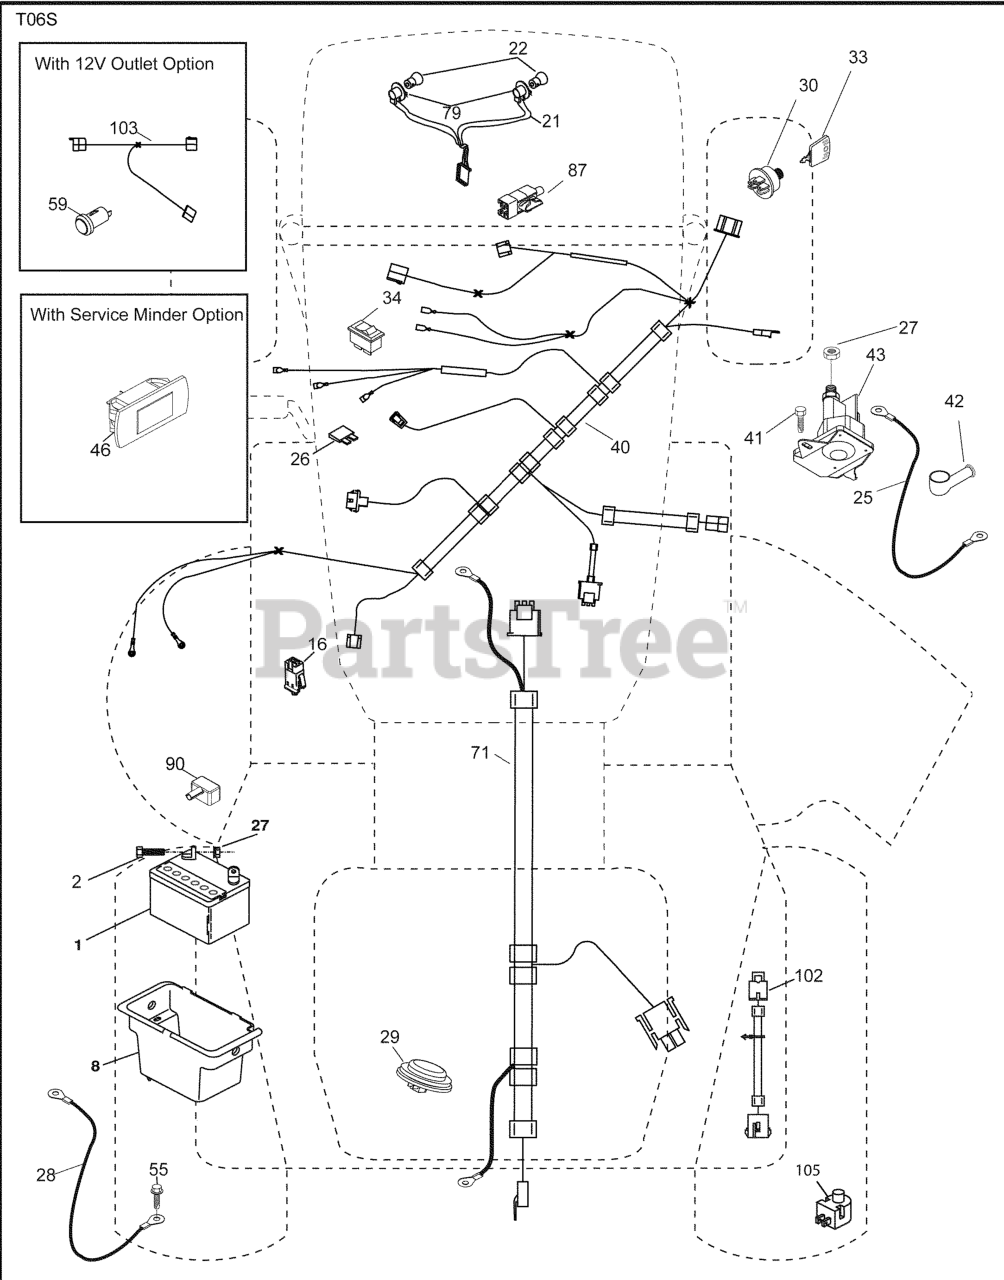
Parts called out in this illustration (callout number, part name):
1	Battery
2	BOLT.HEX.1/4.X.3/4.DICHROMATE
8	BOX.BATTERY.MNT.REAR.L
16	SWITCH INTERLOOK PUSH-IN
21	HARNESS ASSY LIGHT
25	CABLE.STARTER.6G.BL/RED.17.5
26	FUSE 20AMP
27	NUT
28	CABLE.BLACK.18"REAR.BA
29	SWITCH.SEAT.DELTA.OPC.
30	SWITCH.IGN.DELTA.W.LGH.ROS
33	KEY.CHAIN.BLISTER.PACK.GEN.USA
40	HARNESS IGN. DASH
41	SCREW
42	TERMINAL COVER
43	SOLENOID.W/BRASS.PLUNGER
46	RP.GUAGE.SRVCMNDR.HRMTR.
55	SCREW 5/16"
71	HARNESS.IGN.CHASS.TEX.REAR.BAT
79	BULB HOLDER ASM.
87	SWITCH.INTRLCK.CLUTCH.
90	COVER, TERMINAL BATTERY
102	HARNESS PIGTAIL PCH TEX ROS
105	REVERSE SWITCH
